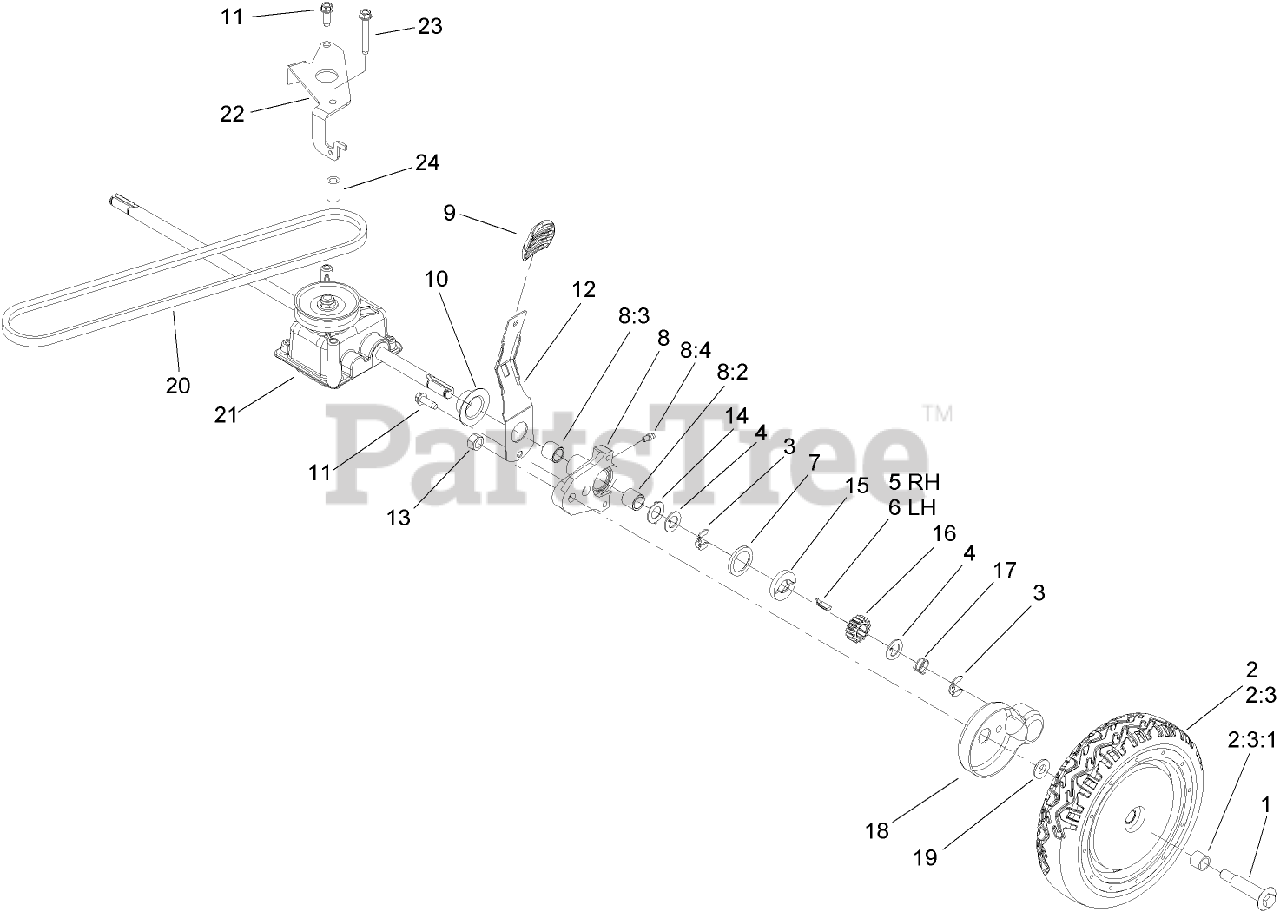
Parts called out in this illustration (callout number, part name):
1	BOLT-SHOULDER
2	8 INCH WHEEL AND GEAR ASM
2:3	Loose Parts Package
2:3:1	BUSHING
3	RING-RETAINING,CLIP
4	WASHER-THRUST, KEYED
5	KEY-ROCKING, RH
6	KEY-ROCKING, LH
7	RING-FRICTION
8	PIVOT ARM ASM
8:2	BUSHING
8:3	BUSHING
8:4	FITTING-GREASE
9	KNOB-LEVER, HOC
10	CAP-END
11	SCREW-HWHTF
12	ARM-SPRING
13	LOCKNUT
14	WASHER-ARM, PIVOT
15	WASHER-CLUTCH
16	GEAR-PINION
17	SPRING-COMPRESSION
18	COVER-WHEEL
19	SPACER-COVER, WHEEL
20	V-BELT
21	GEAR CASE ASM
22	BRACKET-GEARBOX
23	SCREW-HWHTF
24	BUSHING-PLATE, ACTUATOR
